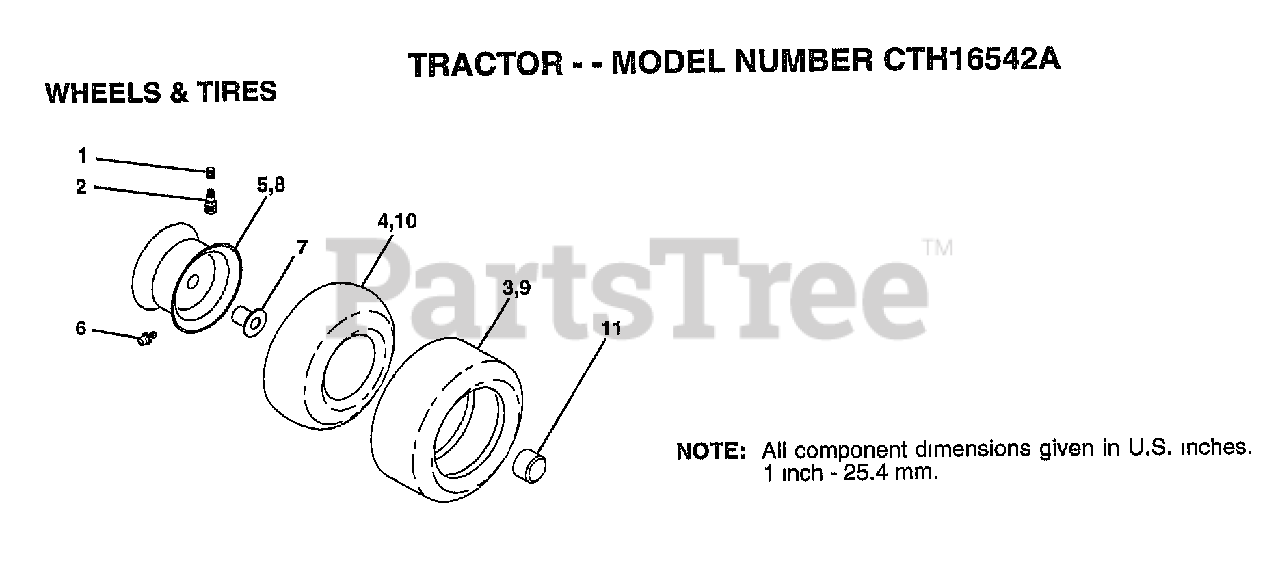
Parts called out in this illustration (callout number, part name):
1	VALVE CAP
2	VALVE STEM LT
4	TUBE.5.3/4.5/6
5	RIM.FRONT.6.YELLO
6	FITTING LT
7	"FLANGE, BEARING"
10	TUBE.18X9.5-8
11	HUB CAP
